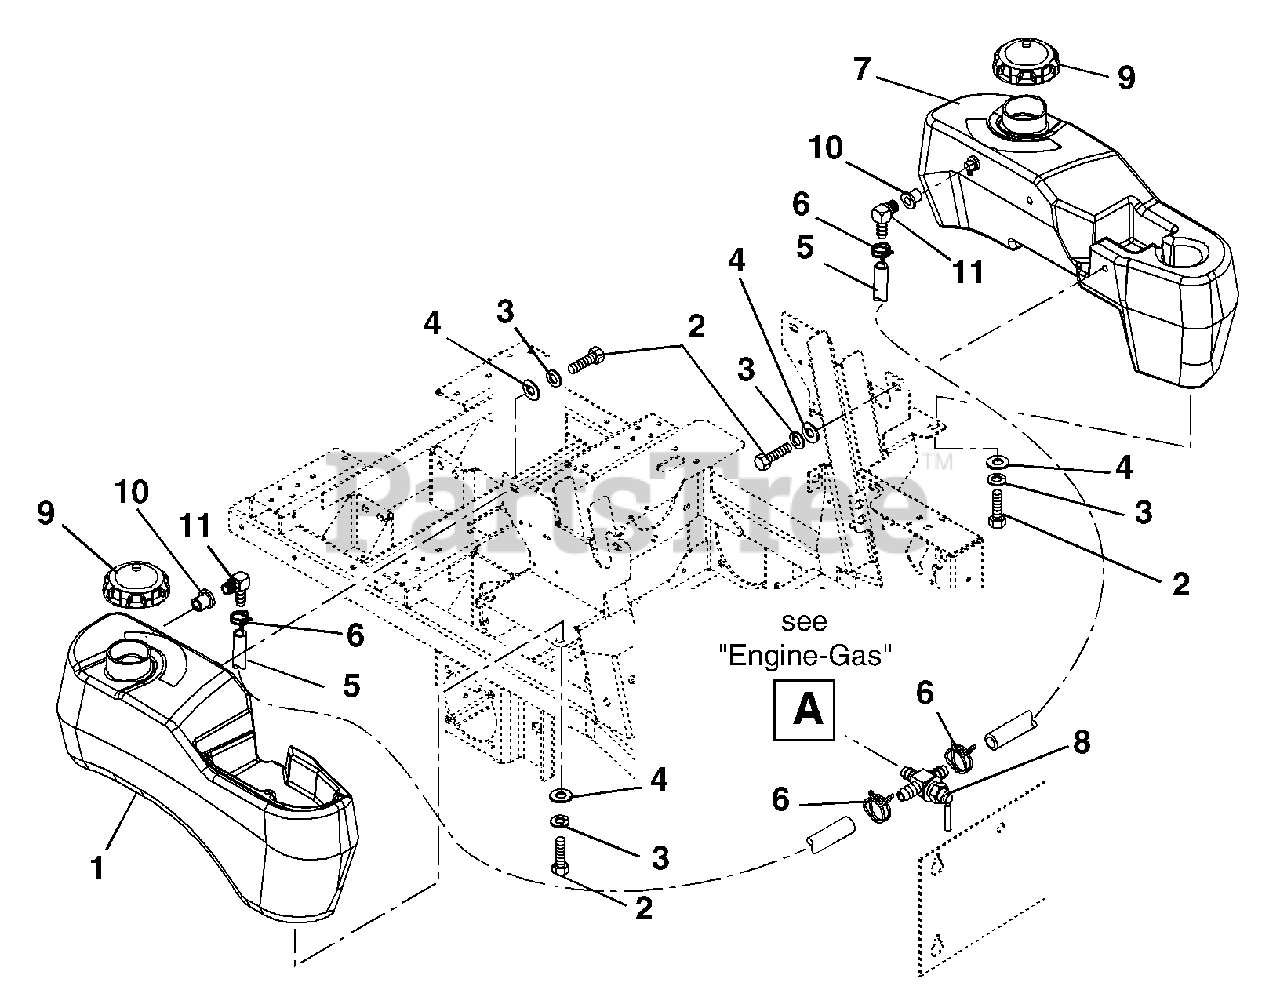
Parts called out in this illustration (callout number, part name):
1	Tank, Gas Fuel-Right Hand (058, 059)
2	Bolt, Hex .31-18 x .75 Grade 5
3	Washer, Locking .31 x .078
4	Washer, Flat Steel .38 x .875 x .083
5	Gas Line-Bulk .25 I.D. (058, 059)
6	Clamp, Hose Wire .49/.51 x .116 (058, 059)
7	Tank, Gas Fuel-Left Hand (058, 059)
8	Valve, Fuel (058, 059)
9	Cap, Gas (058, 059)
11	Fitting, Tank (058, 059)
